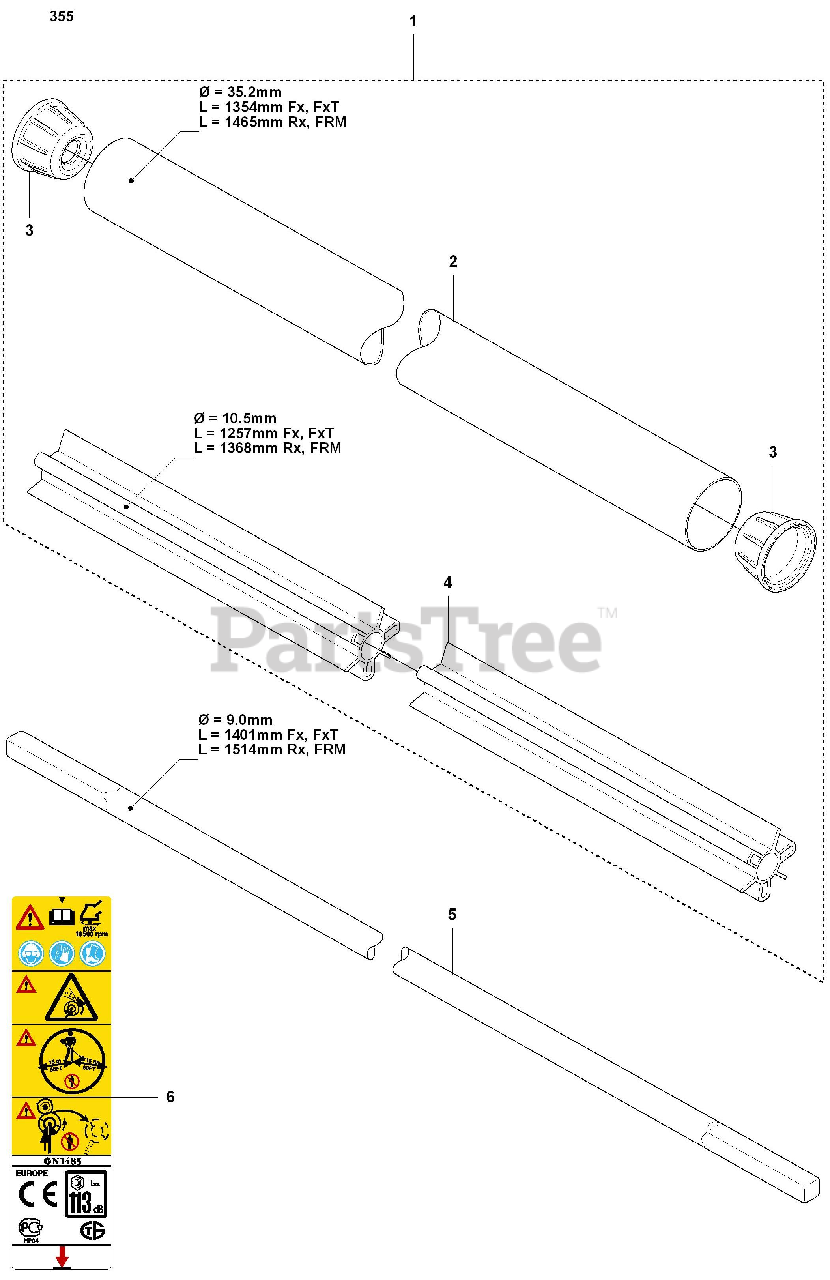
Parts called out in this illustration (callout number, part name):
1	TUBE ASSY
2	TUBE
3	RP SPACER
4	RP BEARING SHAFT
4	%BEARING SHAFT
5	DRIVE SHAFT
